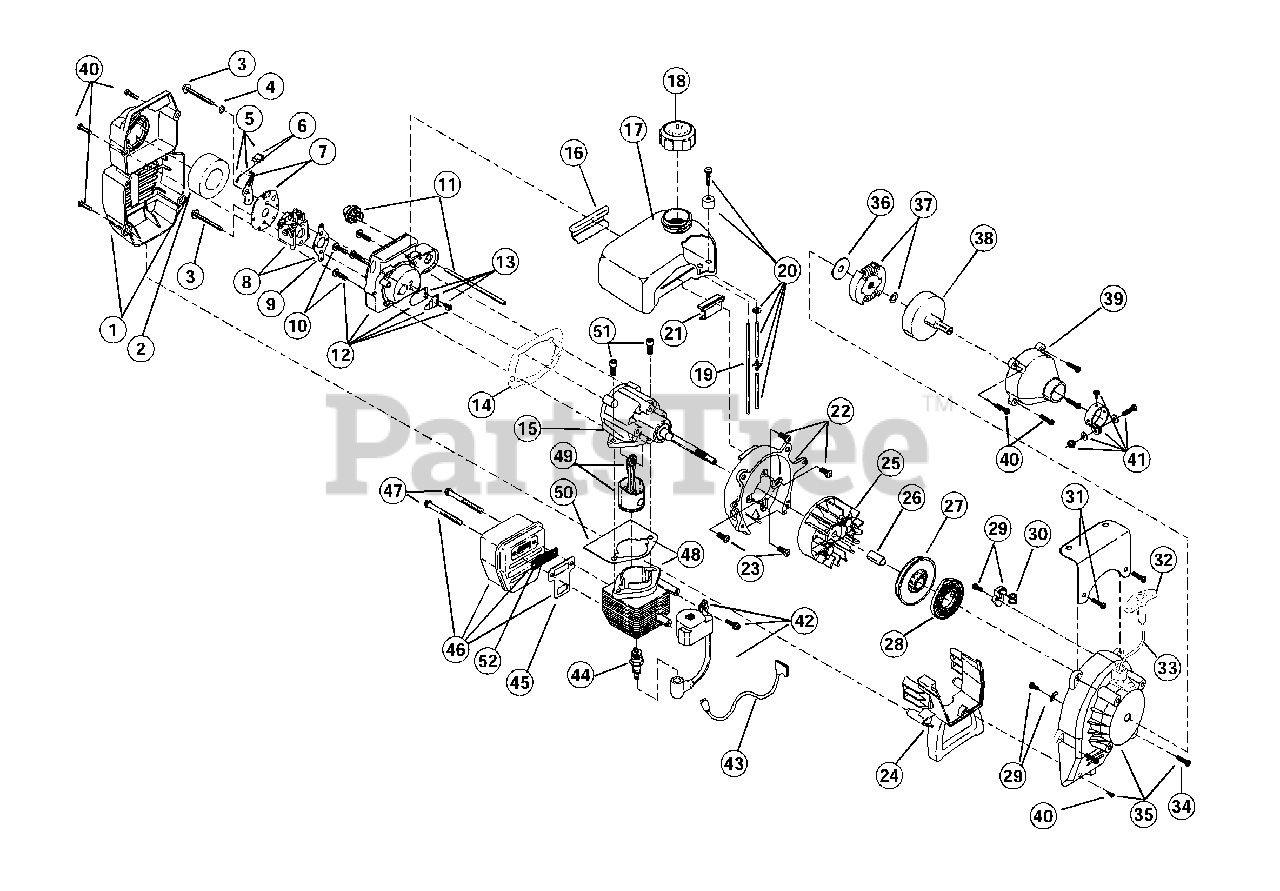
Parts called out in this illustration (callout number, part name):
1	Air Cleaner/Muffler Cover Assembly
2	Air Cleaner Filter
3	Carburetor Mounting Screw Assembly
4	Wavey Washer
5	Choke Lever Assembly
6	Choke Knob and Screw
7	Choke Lever and Plate
8	Carburetor Assembly
9	Carburetor Gasket
10	Carb Mount Screw
11	Primer and Hose Assembly
12	Carb Mount Assembly
13	Reed Assembly
14	Carburetor Mount Gasket
15	Crank Case Service Assembly
16	Rear Mounting Pad
17	Fuel Tank Assembly
18	Fuel Cap Assembly
19	Fuel Return Line
20	Fuel Line Assembly
21	Front Mounting Pad
22	Shroud Assembly
23	Shroud Screw
24	Shroud Extension and Stand
25	Flywheel Assembly
27	Recoil Pulley Assembly
28	Recoil Spring
29	Pulley Retainer Assembly
30	Rope Guide
31	Fuel Tank Guard Assembly
32	Pull Handle
34	Housing Screw
35	Starter Housing Assembly
36	Clutch Washer
37	Clutch Rotor Assembly
38	Clutch Drum Assembly
39	Clutch Cover Assembly
40	Clutch Cover Screw
41	Upper Clamp Assembly
42	Module Assembly
43	Wire Lead
44	Spark Plug
45	Exhaust Gasket
46	Muffler Assembly
47	Muffler Mounting Bolt Assembly
48	Cylinder Assembly
49	Piston and Rod Assembly
50	Cylinder Gasket
51	Cylinder Bolt
52	Spark Arrestor
